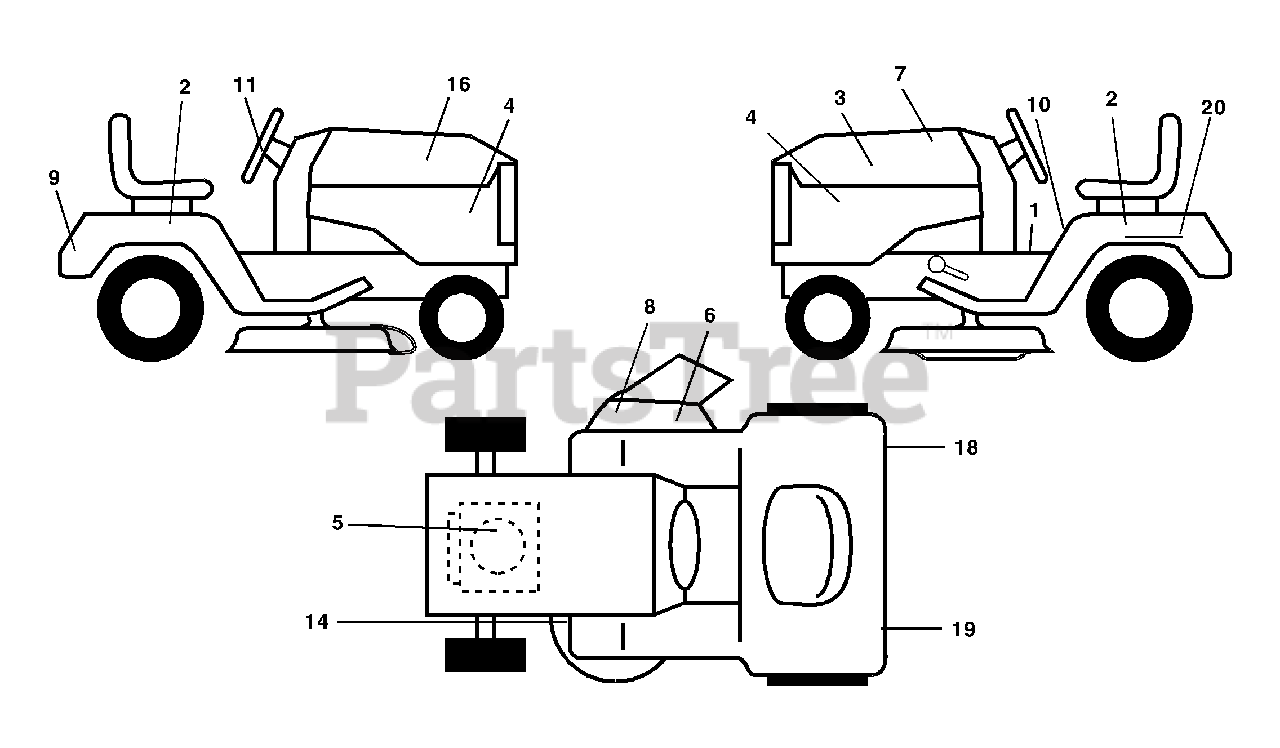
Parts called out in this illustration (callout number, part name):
2	Decal Fender Side
3	Decal Hood LH
4	Decal Side Panel Logo
5	Decal HP Engine
6	Decal Deck "B" 42"
7	Decal Repl. Parts
8	Decal Warning Mult-Language
9	Decal Fender Logo
10	Decal Fender Danger E/F
11	Decal Ins Strg Whl
14	Decal V-Belt Schematic
16	Decal Hood Rh
18	Decal Fender Reflector RH
19	Decal Fender Reflector LH
20	Decal Bat Dan/Psn
